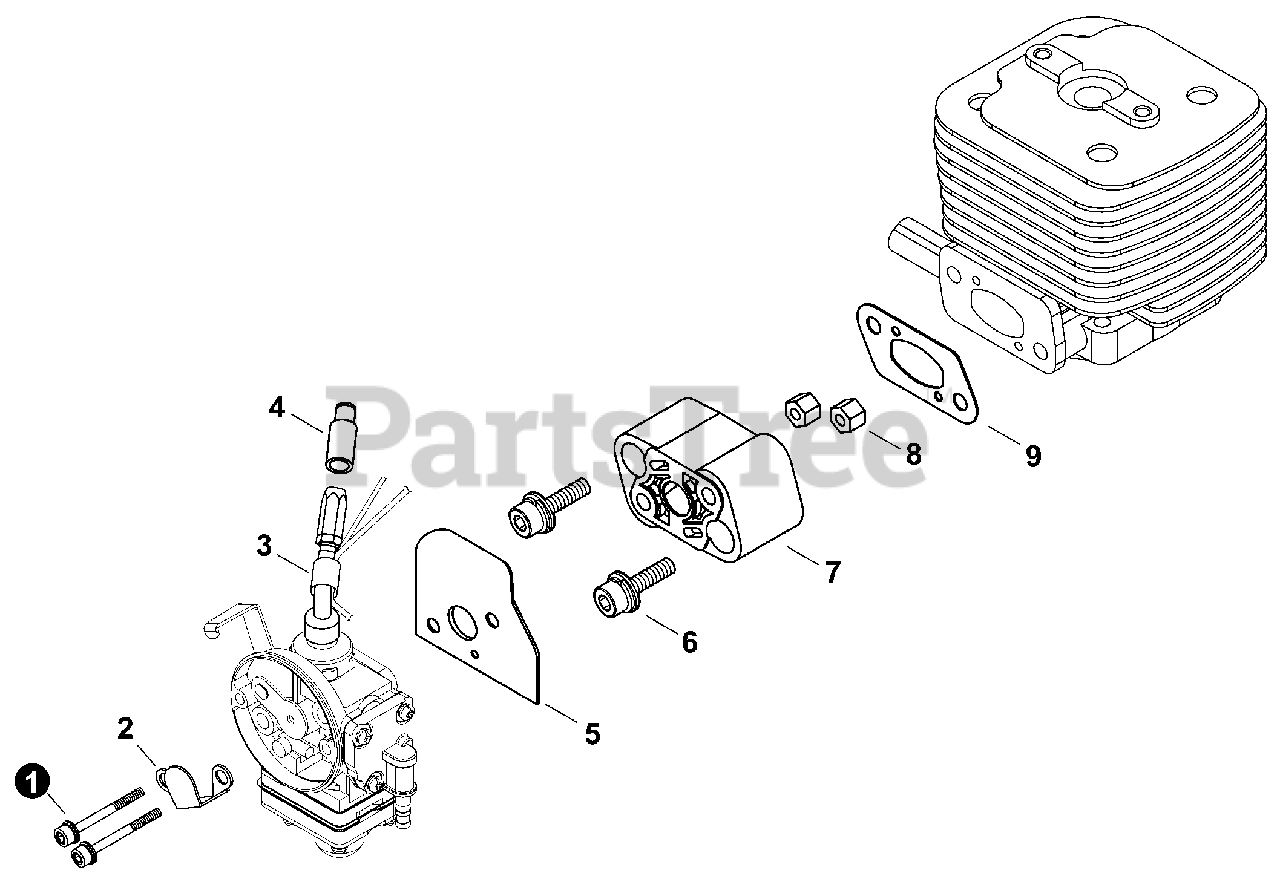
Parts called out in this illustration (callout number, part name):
1	BOLT
2	PLATE, PREVENT
3	TUBE, PROTECTIVE
4	CAP, CARBURETOR
5	GASKET, CARBURETOR
6	BOLT M5x25
7	INSULATOR
8	NUT
9	GASKET, INTAKE
